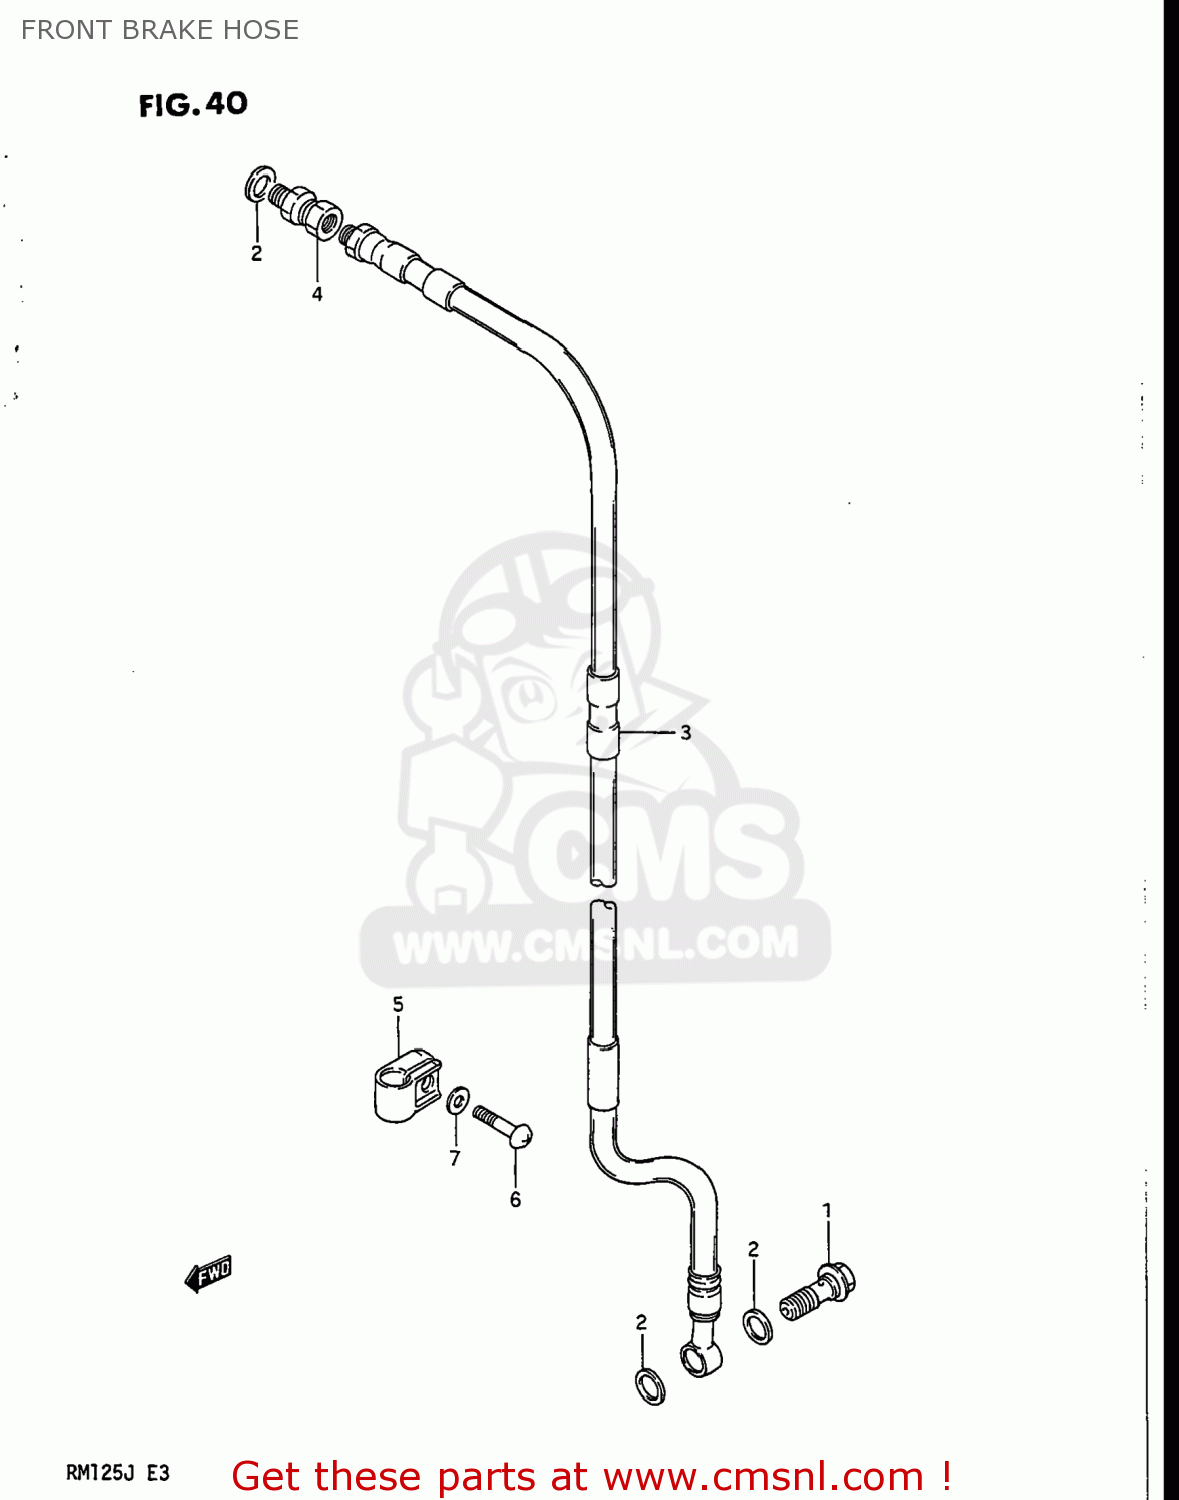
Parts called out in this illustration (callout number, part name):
1	BOLT UNION
2	WASHER(10X15X1.5)
3	HOSE,FRONT BRAKE
4	ADAPTER,BRAKE HOSE
5	CLAMP,FRONT BRAKE HOSE
6	SCREW
7	WASHER
